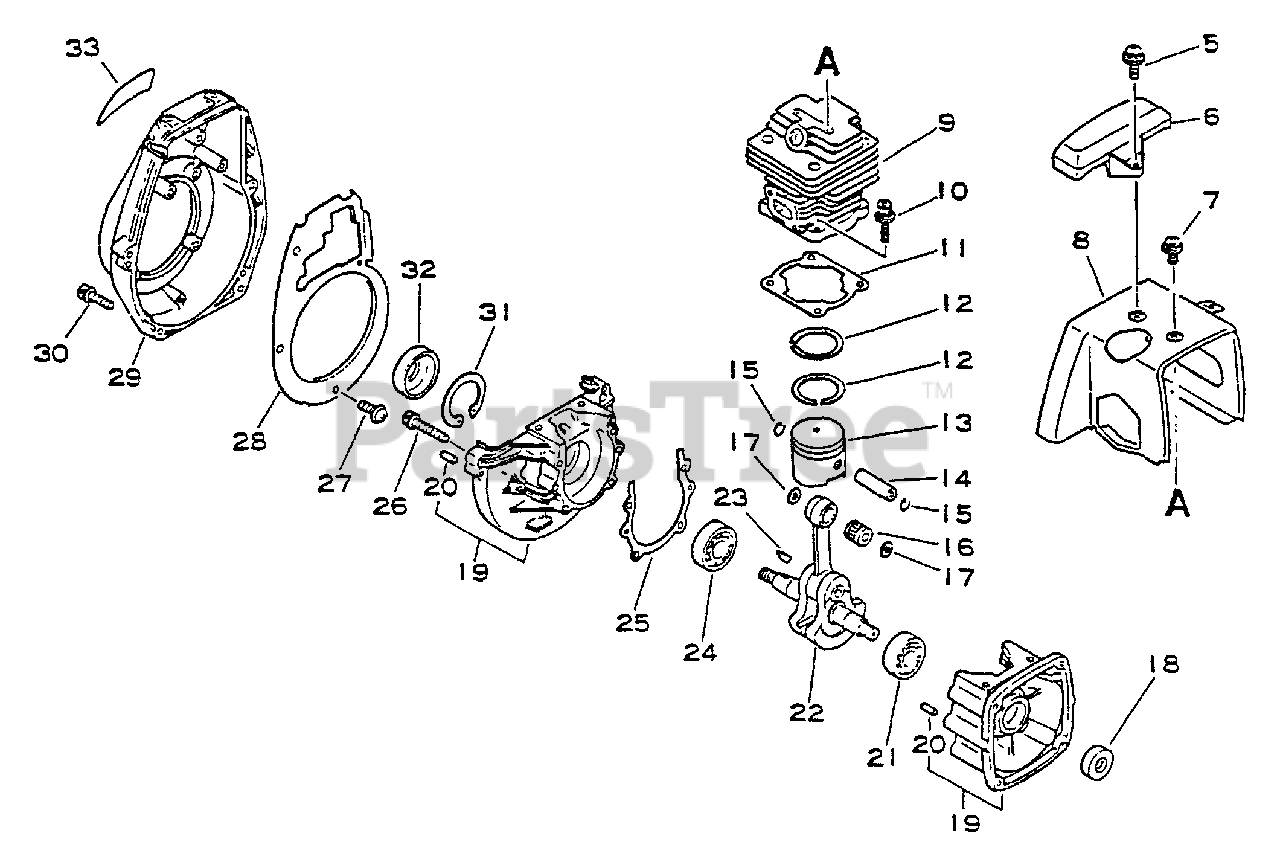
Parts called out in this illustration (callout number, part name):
5	SCREW - 5X14
6	GUARD - TOP
7	SCREW - 5X10
8	COVER, ENGINE
9	CYLINDER
10	SCREW - 5X20
11	GASKET, CYLINDER
12	RING, PISTON
13	RING, PISTON
14	PIN, PISTON
15	RING, RETAINING - 8
16	BEARING, NEEDLE
17	SPACER, PISTON
18	SEAL, OIL - 12
19	CRANKCASE KIT
20	PIN - LOCATING
21	BEARING, BALL - 6201
22	CRANKSHAFT ASSY
24	BEARING, BALL - 6202
25	GASKET, CRANKCASE
26	SCREW - 5X30
27	SCREW - 4X10
28	SHIELD, FAN
29	COVER, FAN - ORANGE
30	SCREW - 5X25
31	RING, RETAINING - 35
32	SEAL, OIL
33	LABEL - MODEL
